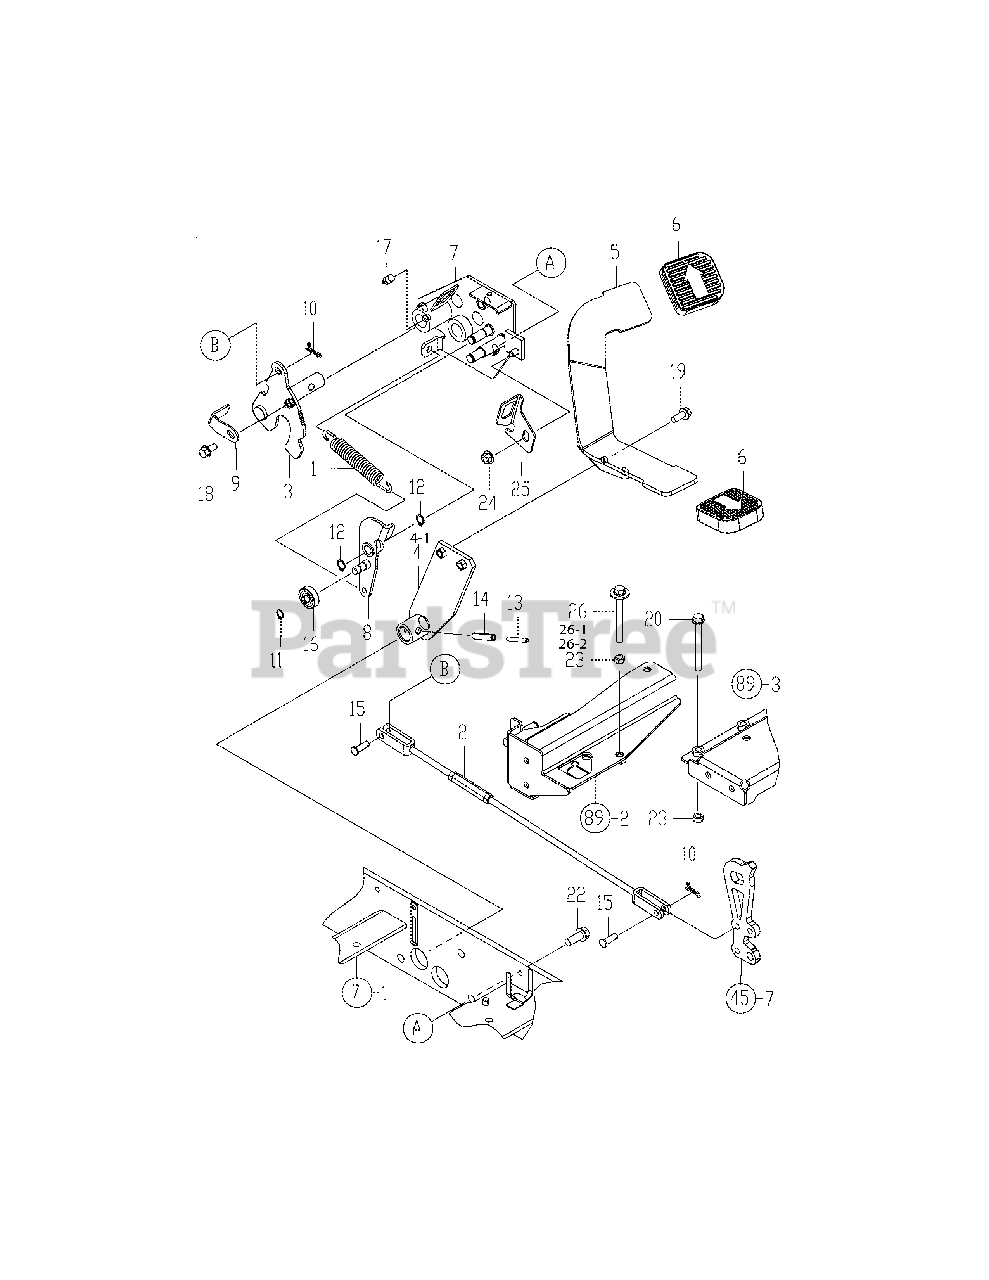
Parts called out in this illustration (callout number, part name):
1	Spring, Return
4	Pedal, Arm Cmp
4-1	Pedal, Arm Cmp
5	Pedal, Hst Cmp
7	Fulcrum, Pedal Cmp
8	Arm, Switch Cmp
13	Pin, 5.0A X 40
14	Pin, 8.0A X 40
16	Bearing, 6200Uu
17	Fitting, Pt 1/8
26	Bolt, Hst Pedal
26-1	Bolt, Hst Pedal
26-2	Bolt M 8X 85 Plated
